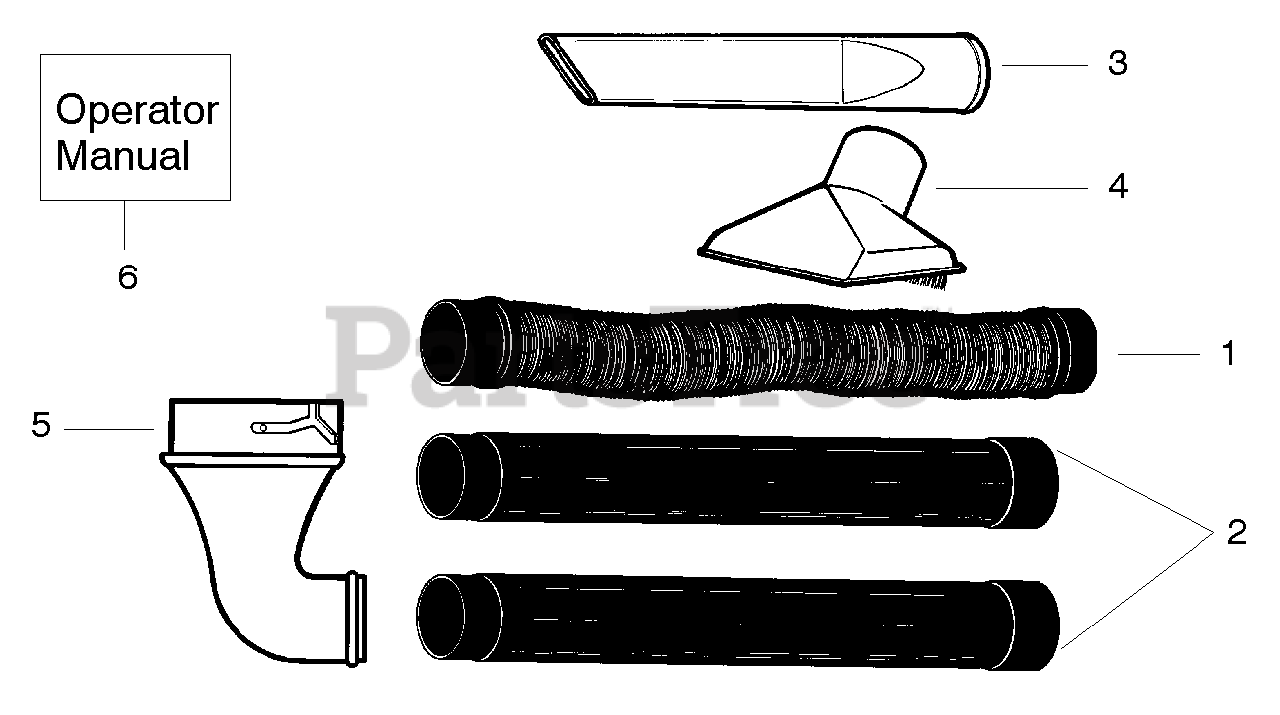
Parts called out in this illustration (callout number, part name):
1	Flex Hose
2	Flex Tube
3	Crevice Tool
4	Floor Brush
5	Flex Adapter
6	Operator Manual
